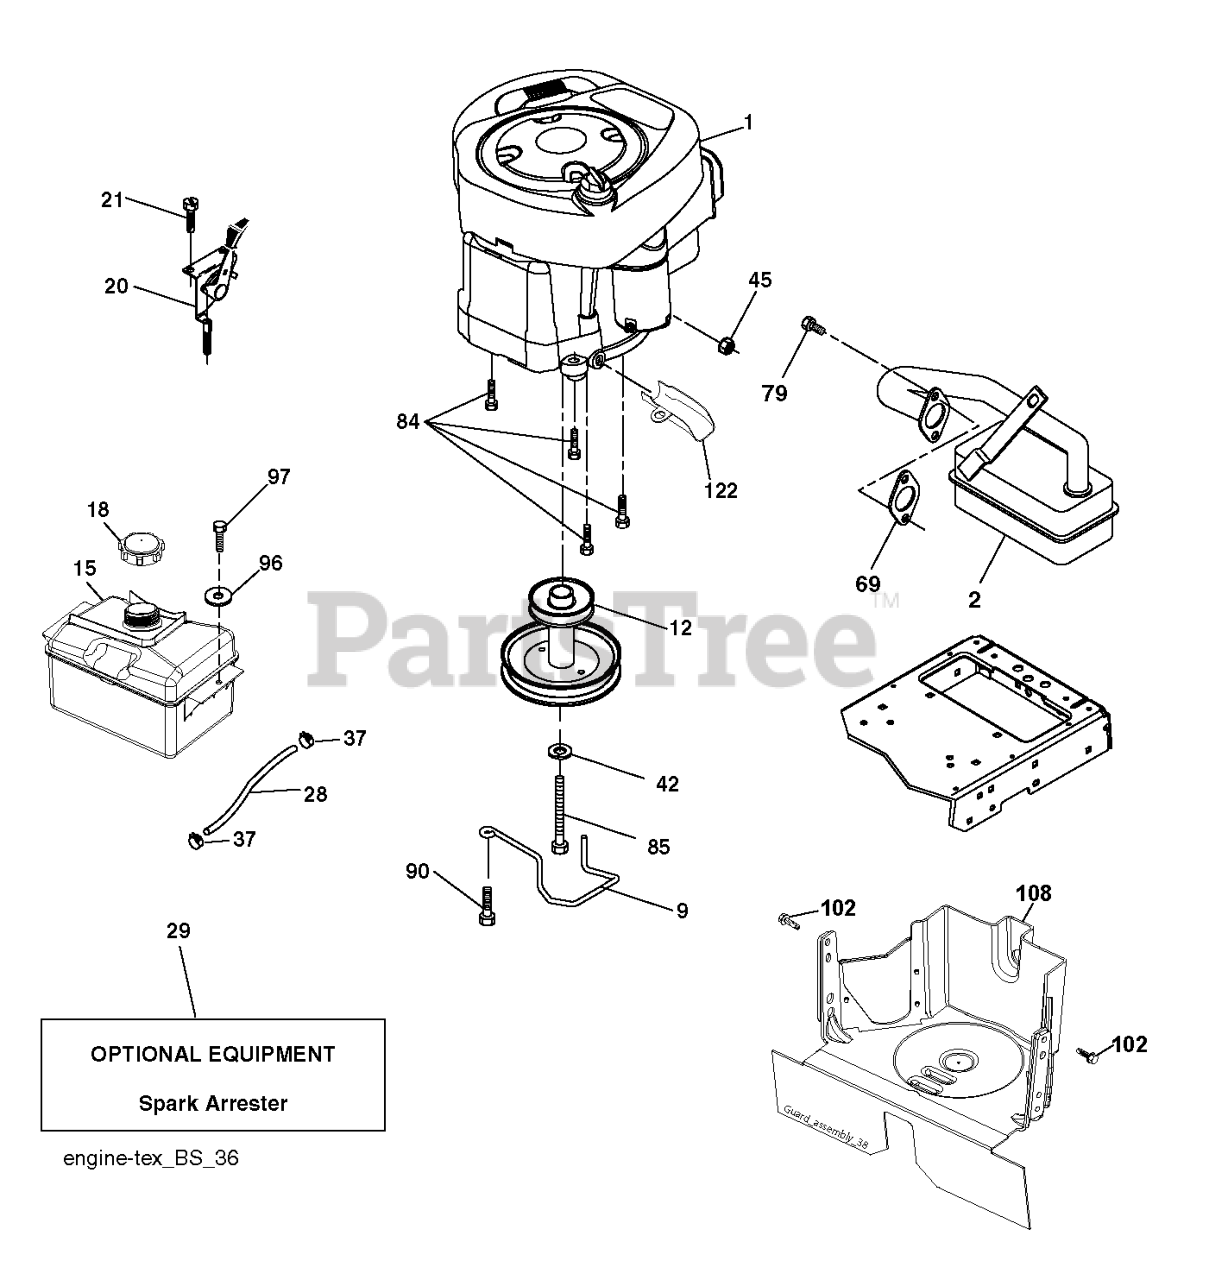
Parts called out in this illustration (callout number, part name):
2	MUFFLER.B&S.MODEL.21.11HP.OHV
9	KEEPER.BELT.ENGINE.3.25 (3 2)
12	PULLEY.ENG.CL.MECH.SLVR.LT/YT
15	RP TANK FUEL FRT 1.5 GAL
18	CAP ASM.FUEL.2.25"FR.
20	CONTROL.TH/CK.C.
21	SCREW.#10 X 0.750.BOS
28	LINE.FUEL.20
29	KIT.SPARK ARRESTOR 794945 B&S
37	HOSE CLAMP
42	LOCKWASHER
45	NUT
69	REPL BY 532 27 22-93
79	SCREW.SOCKET HD.5/16-1
84	SCREW.3/8-16
85	BOLT HEX 7/16-20X4-1/4"
90	SCREW 3/8-16X1
97	SCREW HEXWSHR 1/4-20X3/4
102	SCREW
108	COVER PULLEY
122	EXTENSION DRAIN OIL
